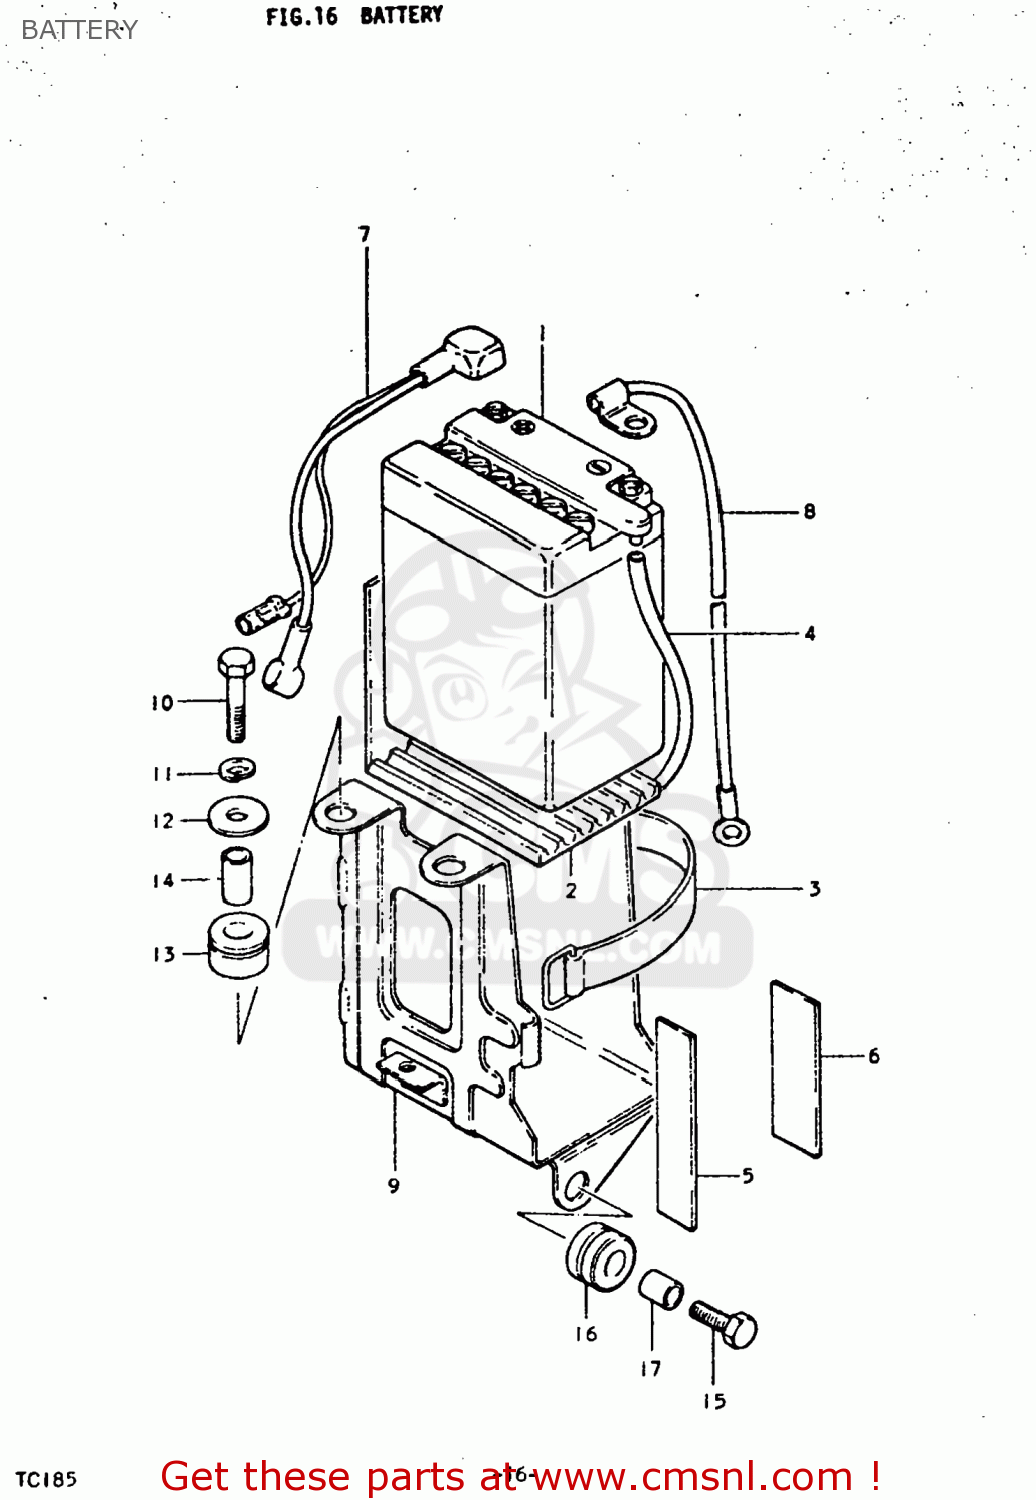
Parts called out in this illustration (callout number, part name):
1	BATTERY ASSEMBLY (12V)
2	CUSHION,BATTERY
3	BAND
4	HOSE,BATTERY EXHAUST
5	PROTECTOR,20X9
6	PROTECTOR(30X80X2)
7	WIRE,BATTERY PLUS
8	WIRE,STARTER MOTOR LEAD
9	HOLDER,BATTERY
10	BOLT
11	LOCK WASHER
12	WASHER
13	CUSHION
14	SPACER (6.1X8X15.5)
15	SCREW
16	CUSHION
17	SPACER
